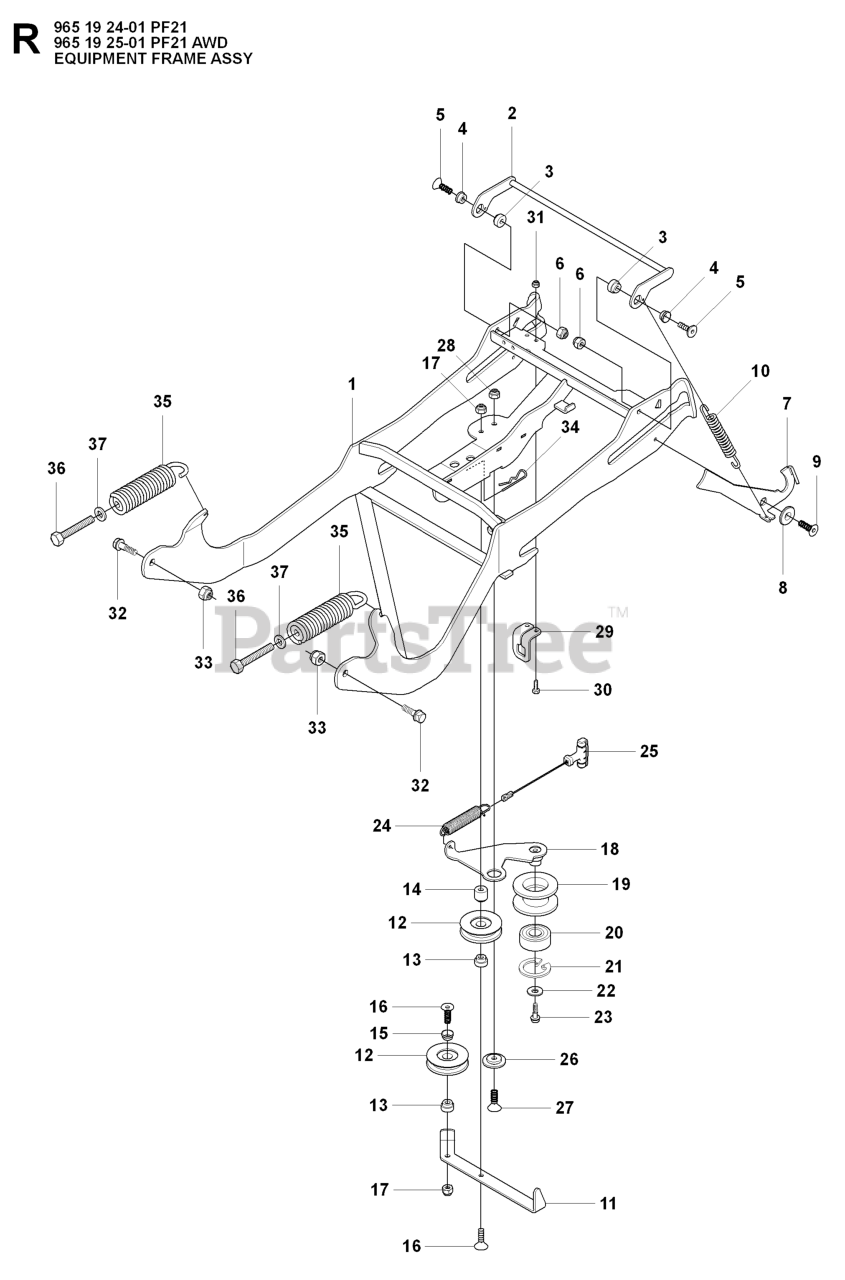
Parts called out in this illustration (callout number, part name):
6	LOCKNUT M8
8	SPACER
9	BOLT REAR WHEEL
12	PULLEY ASSY
17	LOCKNUT M8
19	%PULLEY
20	BALL BEARING 6004-2RS1
21	RETAINING RING
26	WASHER
28	LOCKNUT M8
30	BOLT FLANGE - M6X20
31	LOCKNUT M6
37	WASHER
